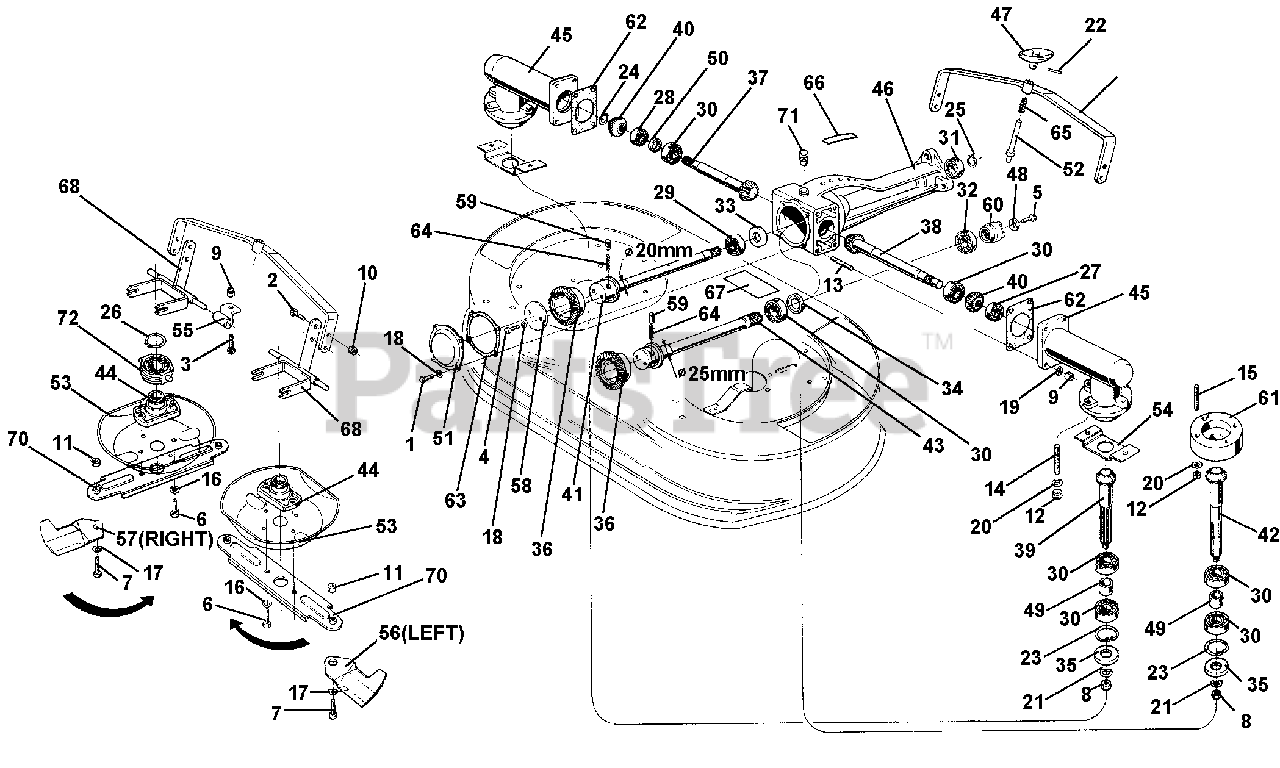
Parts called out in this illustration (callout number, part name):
1	SCREW TE M6 X 14
2	SCREW TE M8 X 12
3	SCREW M8 X 16
4	SCREW M6 X 12
5	SCREW M6 X 20
6	SCREW M8 X 14
7	SCREW M10 X 30
8	NUT, LOW M12
9	NUT, SELF LOCKING M8
11	NUT, SELF LOCKING M10
12	NUT, SELF LOCKING M10 LOW
13	STUD M8 X 40 X 14 X 14
14	STUD M10 X 37 X 19 X 15 8G
15	STUD M10 X 68 X 34 X 15
16	SUPER WASHER 8 DIN 6796
17	SUPER WASHER 10 DIN 6796
18	WASHER, LOCK 6.4
19	WASHER, LOCK 8.4
20	WASHER, LOCK 10.4
21	WASHER, LOCK 13
22	LOCKING PIN 4 X 20 SPRIAL
23	CIRCLIP, INTERN D 52
24	OUTSIDE CIRCLIP
25	CIRCLIP EXTERN. D 20
26	EXT. CIRCLIP D 35
27	BEARING 17 X 40 X 12 6203
28	BEARING 20 X 47 X 14 6204
29	BEARING 20 X 52 X 15 6304
30	BEARING 25 X 52 X 15 6205
31	BEARING 20 X 47 X 14 6204 2RS ST
32	BEARING 25 X 47 X 12 ST 2RS 6005
34	OIL SEAL 25 X 40 X 7
35	OIL SEAL 25 X 52 X 7
37	RIGHT SHAFT
39	ROLL CASING
41	PROPELLER SHAFT
42	BEEL PINION
43	PROPELLER SHAFT
44	BLADE HOLDER HUB
45	SIDE BODY OF 2 BLADE LAWN MOWER
46	LAWN MOWER CENTRAL BODY
48	WASHER 7 X 25 X 4
49	SPACER 25 X 30 X 24
52	SELECTOR PIN
53	PROTECTION DISC
58	DISC, GEAR LOCKING
60	3-TOOTH COUPLING
61	CRANKCASE SPACER
62	SIDE GASKET
64	STOP LEVER SPRING
65	FERRULE SPRING
66	TANSFER FOR LAWN MOWER
68	ADJUSTING LEVER
70	BLADE HOLDER
71	BREATHER CAP 1/4 GAS
